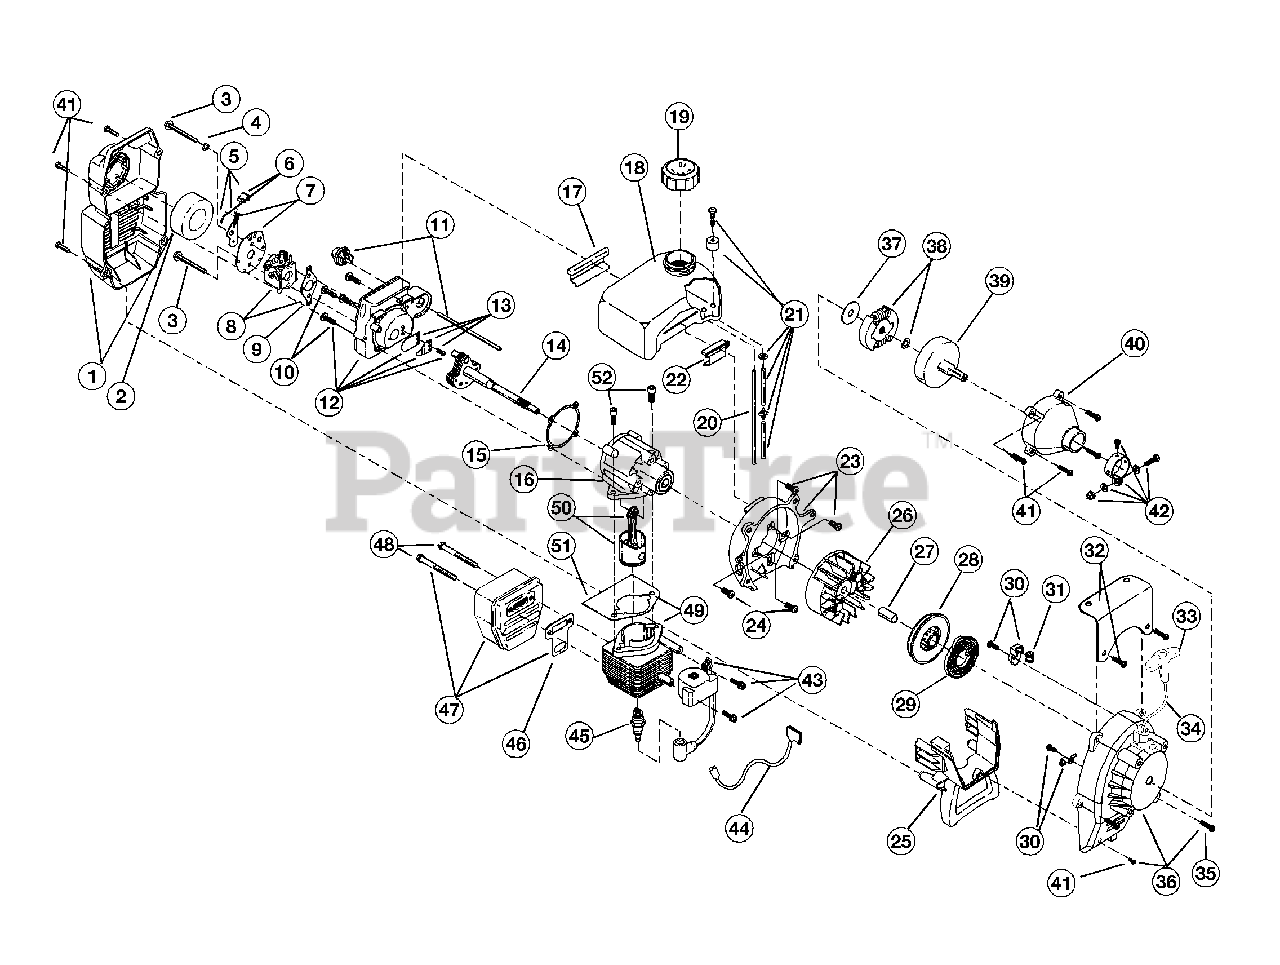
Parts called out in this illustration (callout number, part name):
1	Air Cleaner/Muffler Cover Assembly
2	Air Cleaner Filter
4	Wavey Washer
5	Choke Lever Assembly
6	Choke Knob and Screw
7	Choke Lever and Plate
8	Carburetor Assembly W/Limiter Caps
9	Carburetor Gasket
11	Primer and Hose Assembly
12	Carb Mount Assembly
13	Reed Assembly
14	Power Shaft Assembly
15	Carburetor Mount Gasket
16	Crank Case Service Assembly
17	Rear Mounting Pad
18	Fuel Tank Assembly
19	Fuel Cap Assembly
20	Fuel Return Line
21	Fuel Line Assembly
22	Front Mounting Pad
23	Shroud Assembly
24	Shroud Screw
25	Shroud Extension and Stand
26	Flywheel Assembly
28	Recoil Pulley Assembly
29	Recoil Spring
30	Pulley Retainer Assembly
31	Rope Guide
32	Fuel Tank Guard Assembly
33	Pull Handle
35	Housing Screw
36	Starter Housing Assembly
37	Clutch Washer
38	Clutch Rotor Assembly
39	Clutch Drum Assembly
40	Clutch Cover Assembly
42	Upper Clamp Assembly
43	Module Assembly
44	Wire Lead
45	Spark Plug
46	Exhaust Gasket
47	Muffler Assembly
48	Muffler Mounting Bolt Assembly
49	Cylinder Assembly
50	Piston and Rod Assembly
51	Cylinder Gasket
52	Cylinder Bolt
